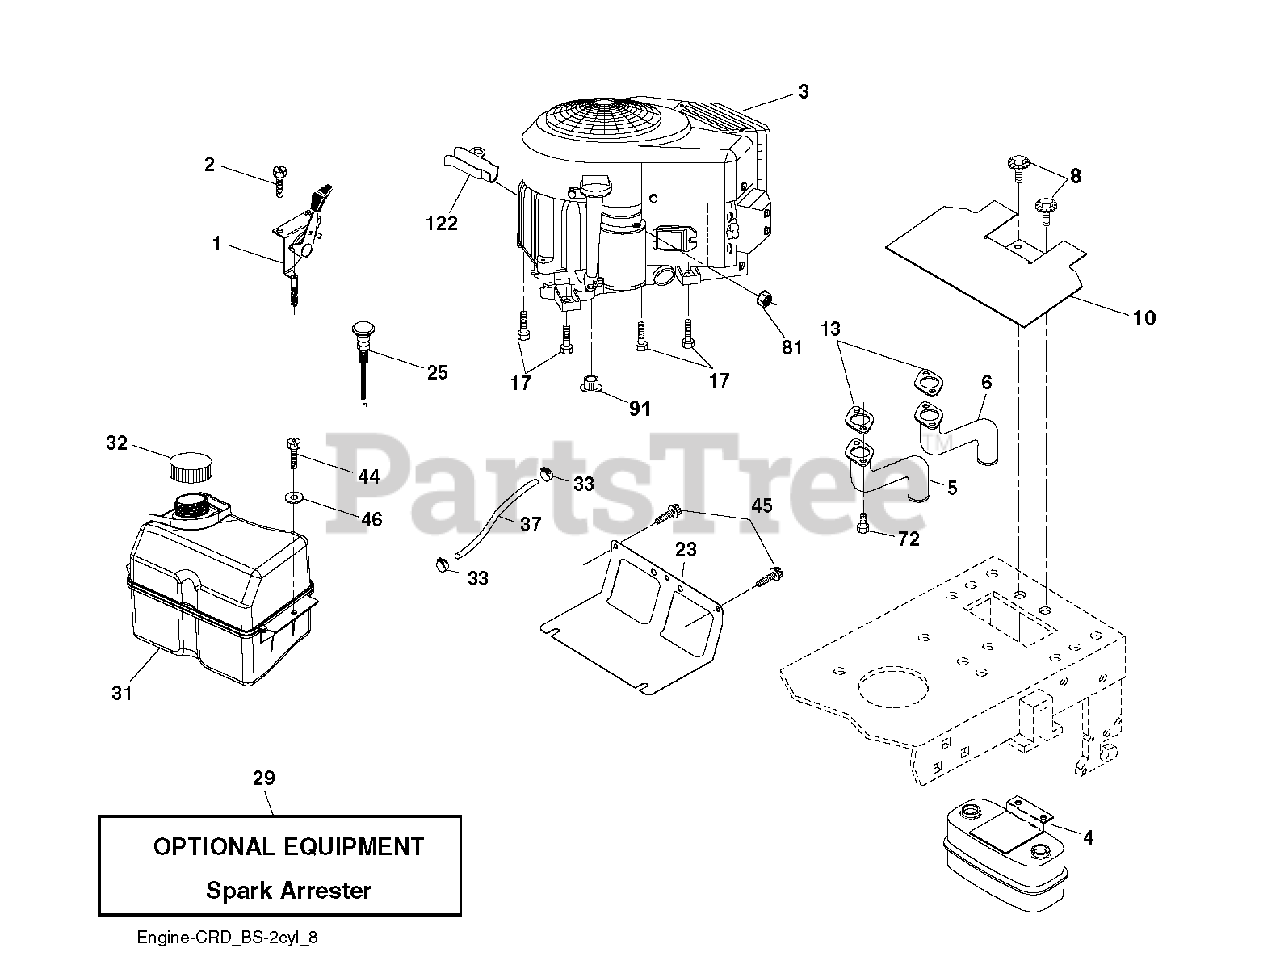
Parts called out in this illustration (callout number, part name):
1	CONTROL, THROTTLE
2	SCREW
4	MUFFLER.TWIN.CYL.LOW.TONE
5	TUBE MANIFOLD LH
6	EXHAUST TUBE RH
8	BOLT, 5/16-18 X 1 3/4
10	RP SHIELD HEAT MUFFLER
13	GASKET.MUFFLER
17	SCREW.3/8-16
23	SHEILD.BROWNING.DBR.GUARD
29	ARRESTER SPARK (OPTIONAL)
32	CAP ASM.FUEL.2.25"FR.
33	HOSE CLAMP
37	LINE.FUEL.20
44	SCREW HEXWSHR 1/4-20X3/4
45	SCREW, 3/8-16X3/4
72	SCREW.SOCKET.HEAD.5/16-18
81	NUT
122	EXTENSION DRAIN OIL
